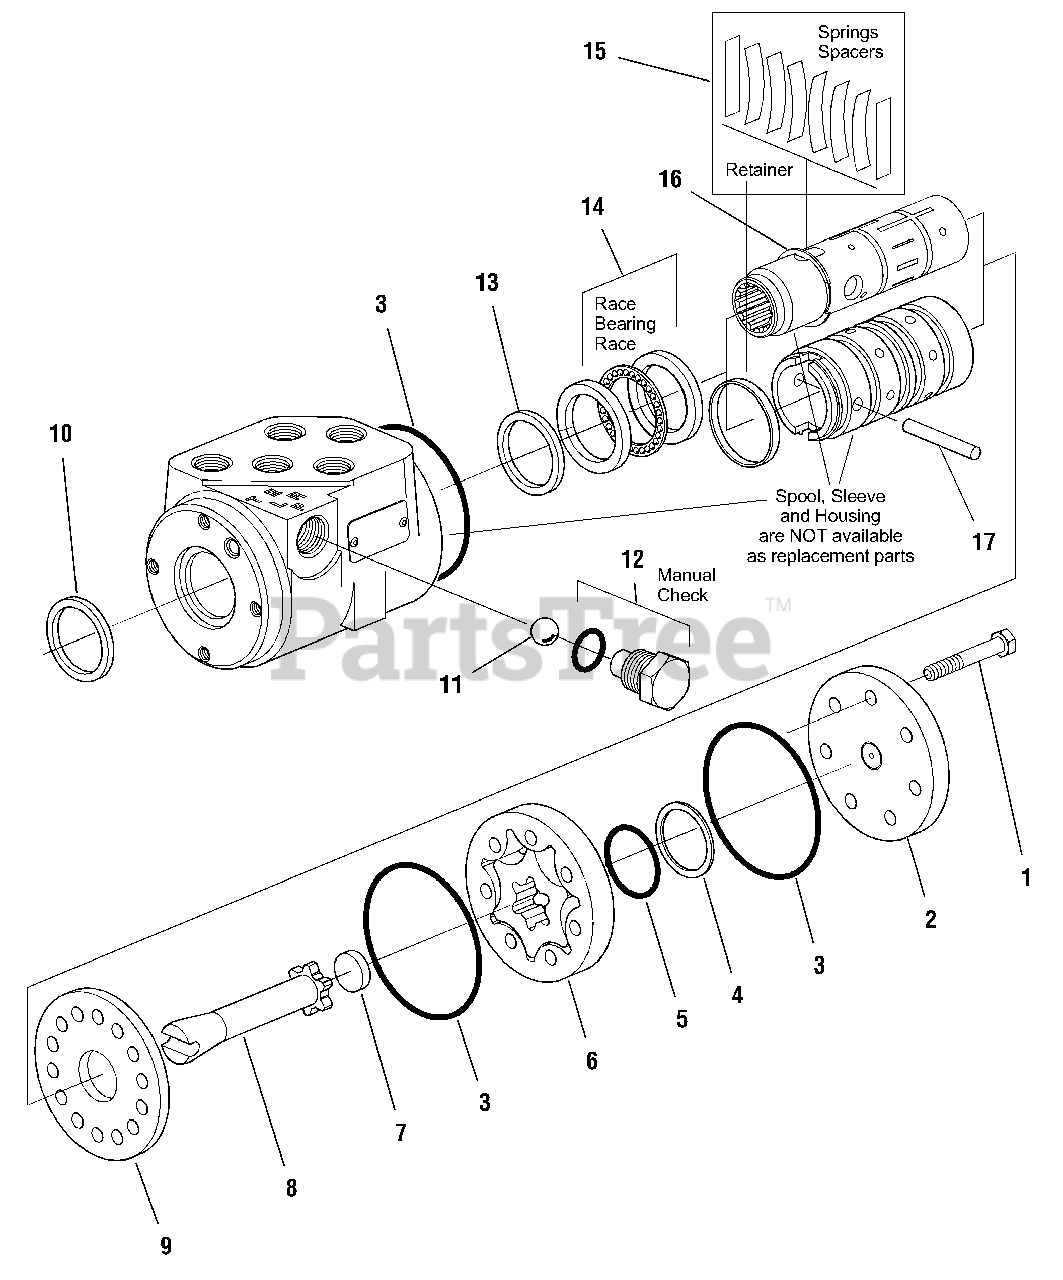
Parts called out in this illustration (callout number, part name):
3	SEAL, O-ring
8	DRIVE
9	PLATE, Wear
12	KIT, Plug & O-ring
14	KIT, Bearing
15	KIT, Centering Spring
16	RETAINING RING, External
